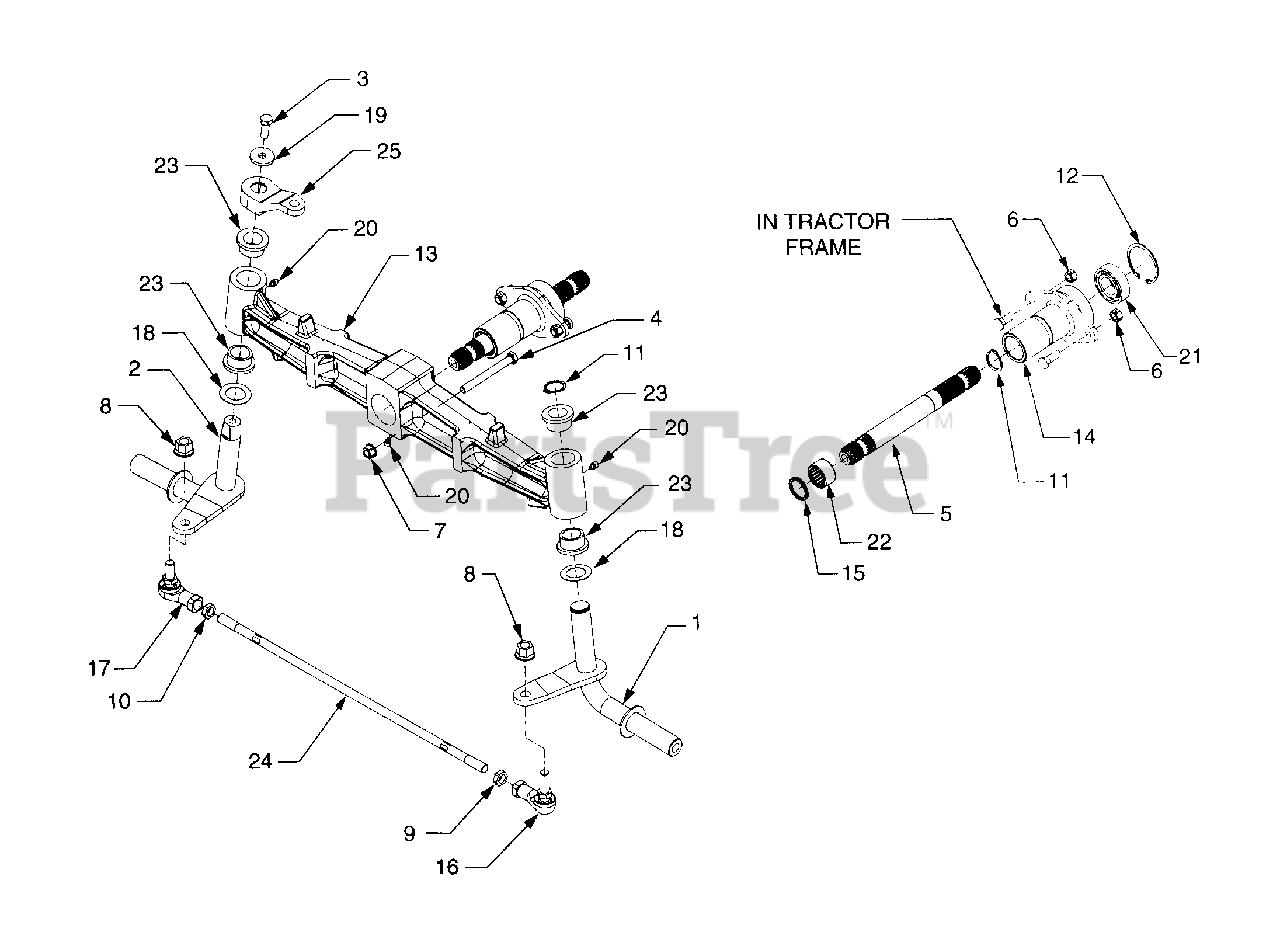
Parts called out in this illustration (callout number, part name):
1	Axle, RH Steering
2	Axle, LH Steering
3	Screw, Hex Cap 3/8-24 x 1.0 GR8
4	Screw, Hex Cap 3/8-16 x 3.5 GR5
5	Shaft, Splined
6	Nut, Hex Center Lock, 3/8-24
7	Nut, Hex Flange Lock, 3/8-16
8	Nut, Hex Flange Lock, M12 x 1.75
9	Nut, Hex - RH, M12 x 1.75
10	Nut, Hex - LH, M12 x 1.75
11	Snap Ring, 1.0 Dia. Shaft
12	Retaining Ring, Internal, 2.0
13	Pivot Axle
14	Axle Carrier
15	Seal, Grease, 1.31 x 1.0
16	Ball Joint, 12MM x 1.75 RH
17	Ball Joint, 12MM x 1.75 LH
18	Washer, Flat, 1.03 x 1.62 x .030
19	Washer, Flat, .406 x 1.25
20	Fitting, Lube, 3/16 Drive
21	Bearing, Ball
22	Bearing, Needle
23	Bearing, Flange
24	Tie Rod, M12 x1.75 RH & LH
25	Steering Arm
